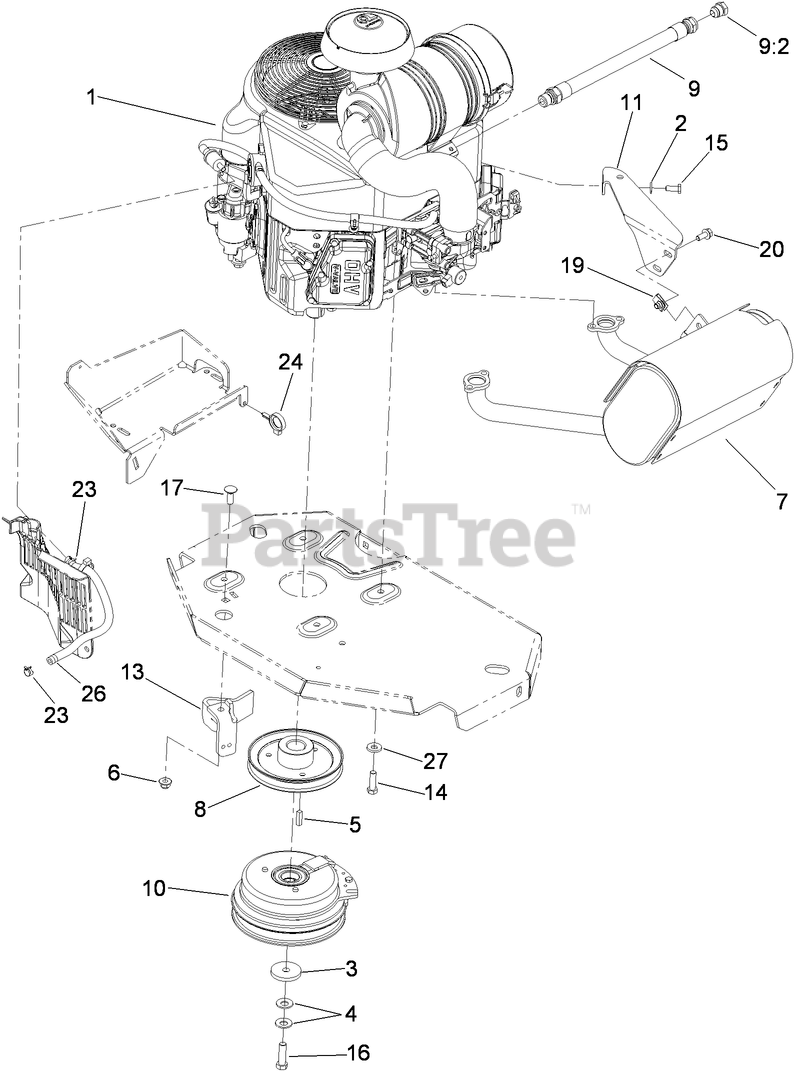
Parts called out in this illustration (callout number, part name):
2	WASHER-SPRING
3	WASHER-CLUTCH
4	WASHER-SPRING
6	NUT-HF, NI
7	MUFFLER
8	SHEAVE
9	OIL DRAIN HOSE ASM
10	CLUTCH KIT
11	BRACKET-MUFFLER
13	CLUTCH-ANCHOR
14	SCREW-HH
15	SCREW-HH
16	SCREW-HH, W/LOCTITE
17	SCREW-CARR
19	NUT-U
20	SCREW-HHF
23	CLAMP-HOSE
24	CLAMP-HOSE
26	HOSE-FUEL
27	WASHER-BELLEVILLE
